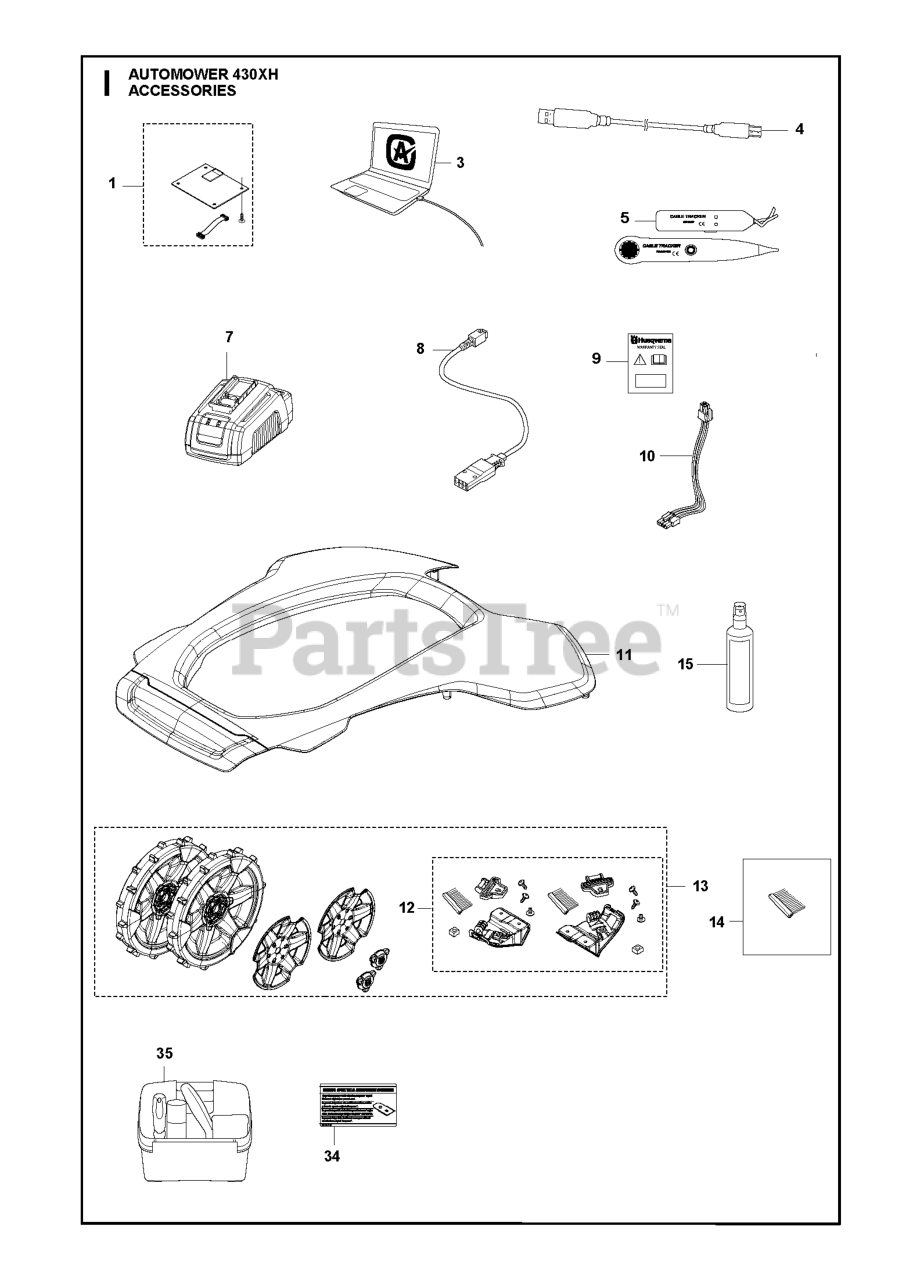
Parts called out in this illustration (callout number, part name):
1	CONNECT MODULE 2G / 3G
4	CABLE WHITE ALT GREY
5	TEST EQUIPMENT
7	CHARGER BATTERY TEST
8	CABLE ASSY QUICK CHARGER
9	LABEL WARRANTY SEAL DEALER
10	WIRING ASSY BATTERY CABLE
11	BODY KIT WHITE 430X 2018+
11	BODY KIT ORANGE 430X 2018+
12	BRUSH KIT 430/450
13	REAR WHEEL KIT W/ BRUSHES
14	WHEEL BRUSH REFILL KIT
34	DECAL WARNING ORIGINAL BLADE E
35	CLEANING AND MAITENANCE KIT AM
